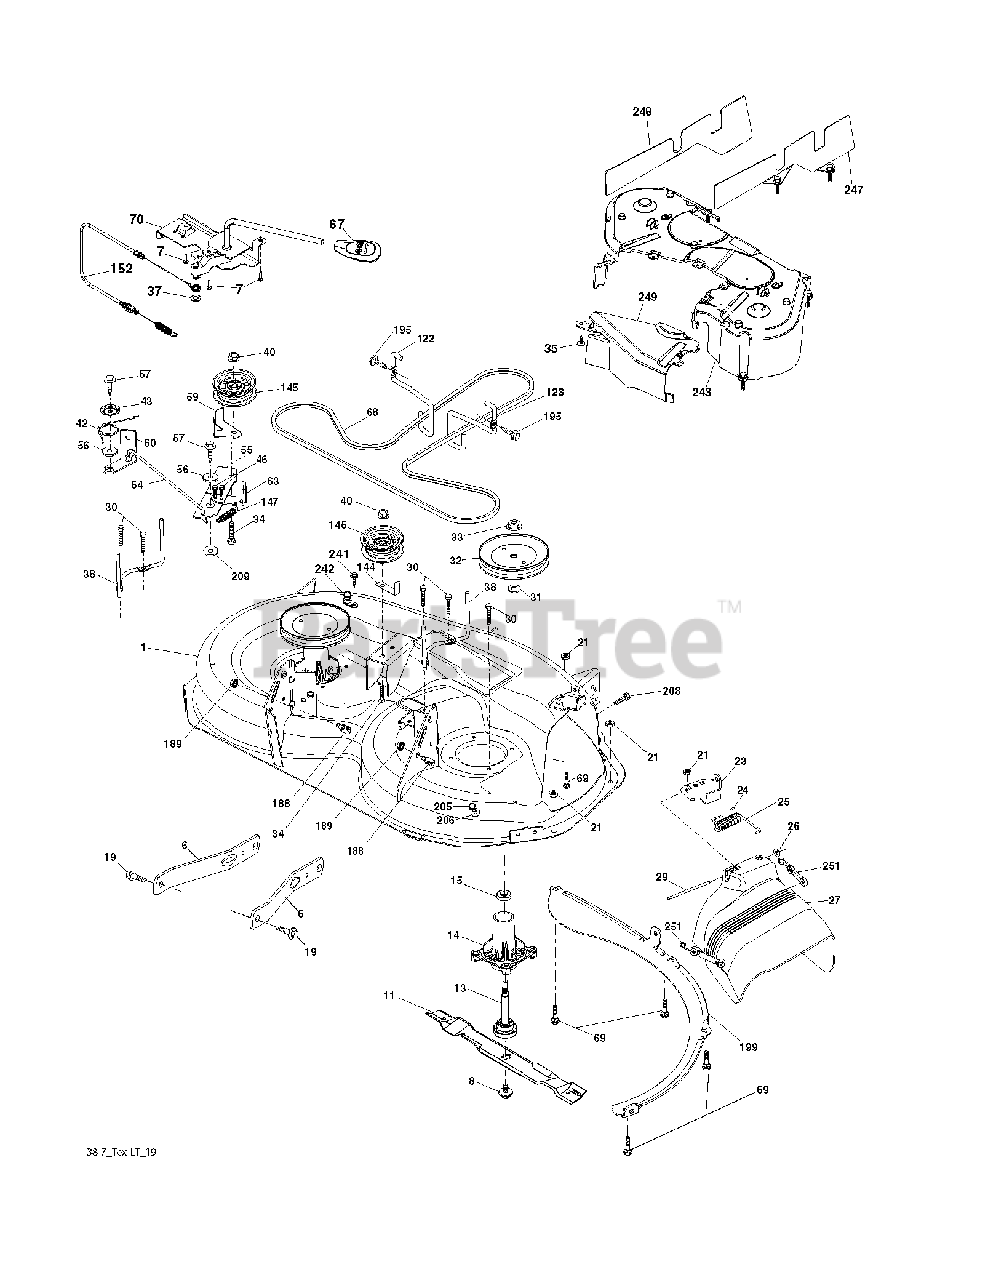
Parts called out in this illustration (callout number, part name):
6	ARM.SUSPENSION.MOWER.R
7	SCREW.#10 X 0.750.BOS THREAD
8	BOLT.WASHER.ASM.7/16-2
11	BLADE 38" PREMIUM
13	SHAFT.ASM.MDRL.N/GREASE.38
14	HOUSING MANDREL
19	BOLT.SHOULDER
21	LOCKNUT
23	BRKT.DEFLECTOR.38"2005+
24	CAP-SLEEVE LT
25	SPRING.TORSION.DEFLECT
26	NUT PUSH M
29	ROD.HINGE
30	SCREW, WASHER HEAD
31	WASHER.SPACER.MANDREL
32	PULLEY.MANDREL.5.0.PD.38"
33	NUT.FLANGE.LOCK.TOP
34	BOLT.3/8-16X1.50
35	FASTENER.XMAS.TREE
38	KEEPER BELT LH MANDREL
40	NUT LOCK FLG 3/8-16 UNC
42	SPRING.TORSION.BRAKE
43	SRPING.TORSION.RETAINE
46	SCREW.1/4-20X5/8
55	IDLER.ARM
56	SPACER.RETAINER
57	SCREW 3/8-16X1
59	GUARD, BELT
60	ARM BRAKE MOWER RH 38"
63	ARM BRAKE MOWER RH
64	LINK BRAKE
67	HANDLE.CLUTCH.CABLE.LT
69	BOLT
70	CLUTCH.ASM.MANUAL.LT.PRED
122	KEEPER BELT ENGINE LH
123	KEEPER BELT RH
144	KEEPER BELT
145	PULLEY.IDLER.48"PRIMARY
147	SPRING RETURN
152	CABLE.CLUTCH.MANUAL.
188	STUD.FASTNER.W/ANTI-ROTATE
189	NUT LOCK HEX FLANGE 5/16-18
195	SCREW, 3/8-16X3/4
199	BAFFLE VORTEX
205	SCREW
208	SCREW 3/8-16X1/2
209	WASHER 12/32X2X10GA
242	PORT.WASHOUT
